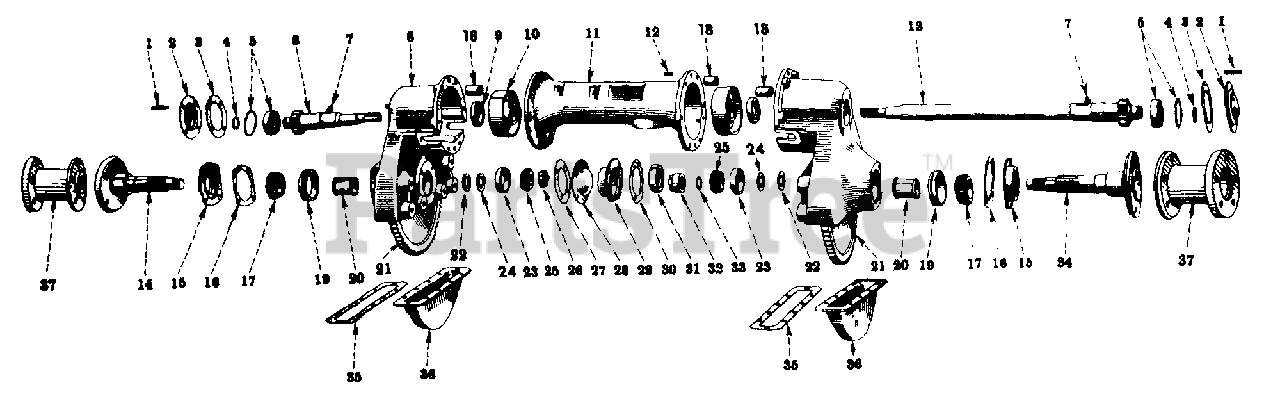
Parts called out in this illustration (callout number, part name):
1	STUD, DIFFERENTIAL SHAFT OUTER BEARING COVER
2	RETAINER, DIFFERENTIAL SHAFT BEARING
3	GASKET, DIFFERENTIAL SHAFT BEARING RETAINER
4	RING, DIFFERENTIAL SHAFT BEARING LOCK
5	BEARING, DIFFERENTIAL SHAFT BALL
6	SHAFT, DIFFERENTIAL LH - 12 TEETH
7	KEY, 3/16 X 1 WOODRUFF NO 13 - BRAKE DRUM
8	HOUSING ASSY, REAR AXLE
8	HOUSING ASSY, REAR AXLE LH
8	HOUSING ASSY, REAR AXLE RH
9	SEAL, DIFFERENTIAL SHAFT PINION OIL
11	HOUSING ASSY, DIFFERENTIAL SHAFT
12	DOWEL, DIFFERENTIAL SHAFT HOUSING
13	SHAFT, DIFFERENTIAL RH - 12 TEETH
14	AXLE, LH REAR
15	SEAL, REAR AXLE OIL
16	GASKET, REAR AXLE OIL SEAL
17	BEARING ASSY, REAR AXLE OUTER CONE
18	BUSHING, ACTUATING TOGGLE
19	BEARING, REAR AXLE OUTER CUP
20	SPACER, REAR AXLE BEARING
21	GEAR REAR AXLE DRIVE -70 TEETH
22	SPACER, REAR AXLE DRIVE GEAR
23	BEARING, REAR AXLE INNER CUP
24	SHIM, REAR AXLE DRIVE GEAR
25	BEARING ASSY, REAR AXLE INNER CONE
26	NUT, 9/16 LH REAR AXLE
27	GASKET, LH REAR AXLE BEARING CAP
28	CAP, IH REAR AXLE BEARING
29	RETAINER W/OIL SEAL, 382220-R91, REAR AXLE NUT RH
30	GASKET, OIL SEAL RETAINER OR RH BRG CAP
31	SEAL, REAR AXLE NUT RH RETAINER OIL
32	NUT, 1-1/8 THICK RH REAR AXLE
33	RING, REAR AXLE NUT RH SEAL
34	AXLE, RH REAR - CUB TRACTORS
35	GASKET, REAR AXLE HOUSING PAN
36	PAN, REAR AXLE HOUSING
37	EXTENSION, REAR AXLE
